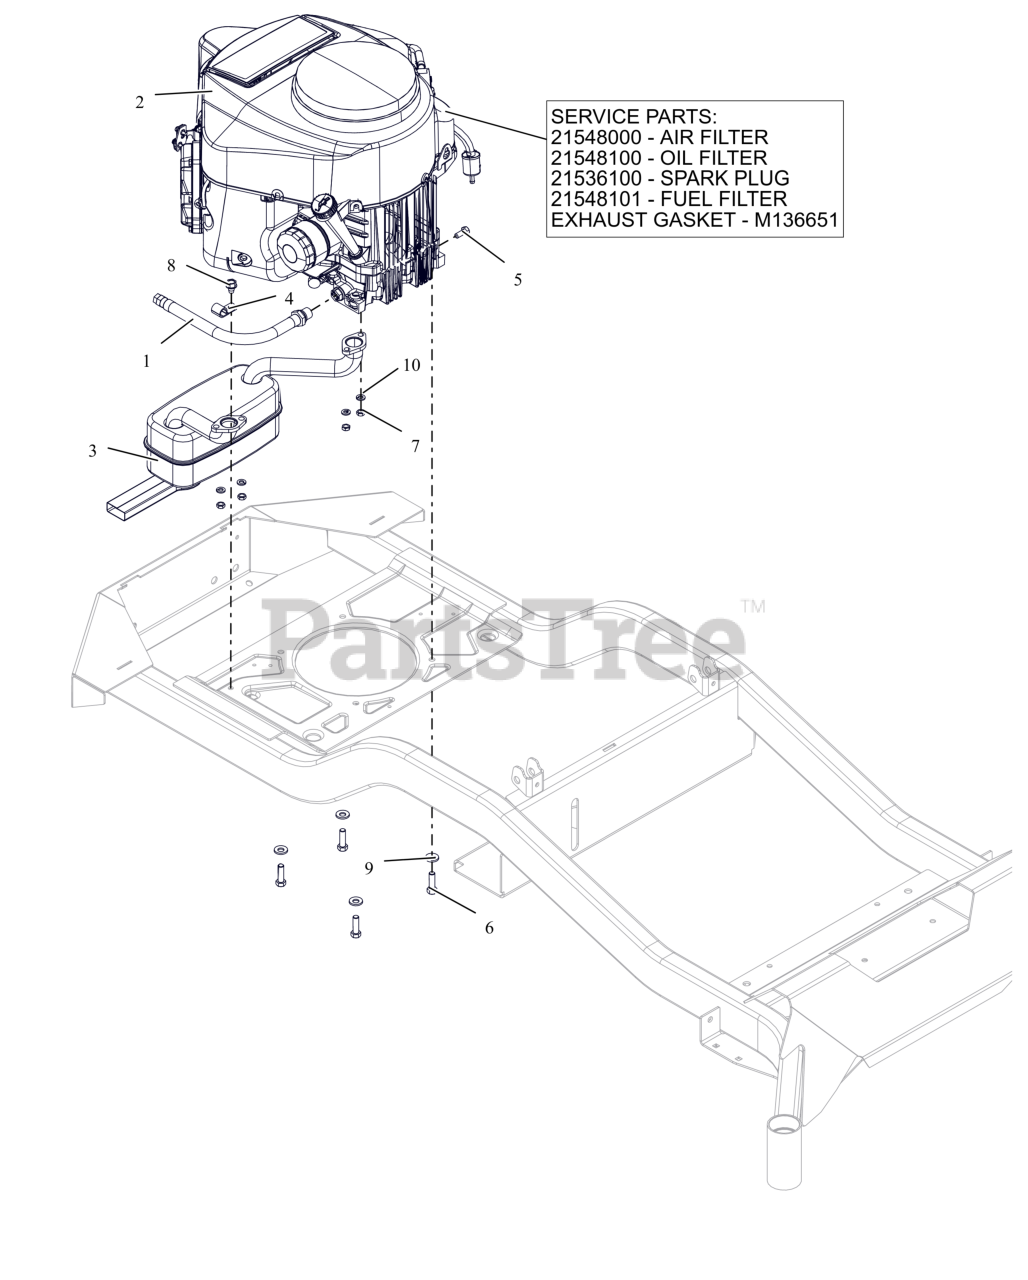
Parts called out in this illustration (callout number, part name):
1	HOSE, OIL DRAIN
2	ENGINE, KAWASAKI FR691 23HP
2	AIR FILTER, KAWASAKI FR
2	OIL FILTER, KAWASAKI FR
2	PLUG, SPARK
2	FUEL FILTER-KAWASAKI FR
2	GASKET, MUFFLER #
3	MUFFLER, KAWASAKI
4	J-CLAMP
5	BLT, HEX M8-1.25X20 G8.8 ZCC
6	BLT, HEX .38-16X1.25 G5 ZCC NT
7	NUT, LK-CTR-JAM M8-1.25 GR8.8 ZC120
8	SCR,TAP .375-16X.50 HWH TR ZCC
9	WASHER, 3/8" SPRING DISC
10	WSHR,LK-REG .312X.078 ZCC
